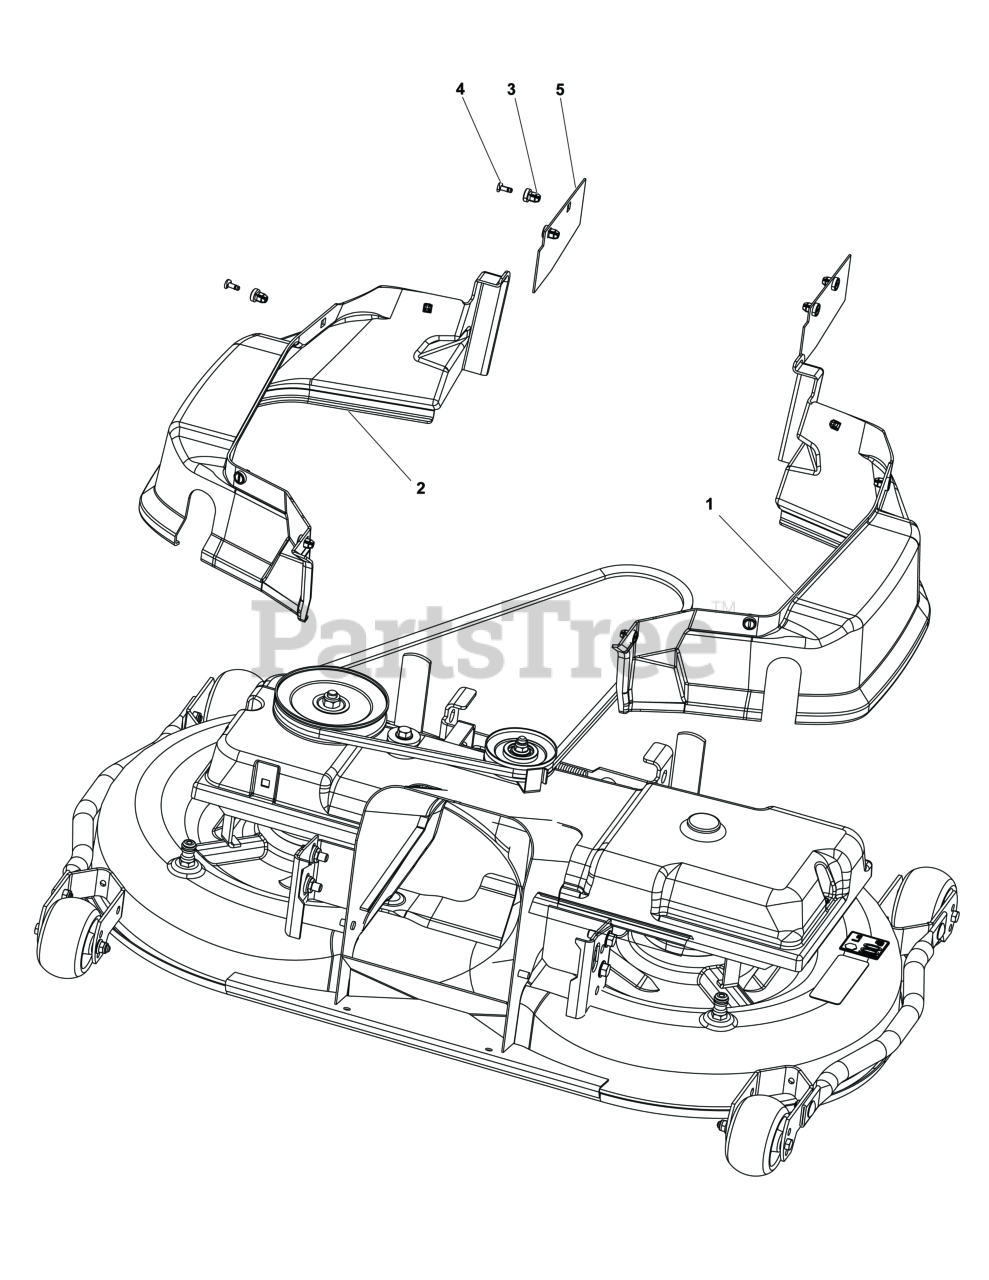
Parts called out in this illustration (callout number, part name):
1	COVER, Belt
2	COVER, Belt
5	COVER, Clutch
